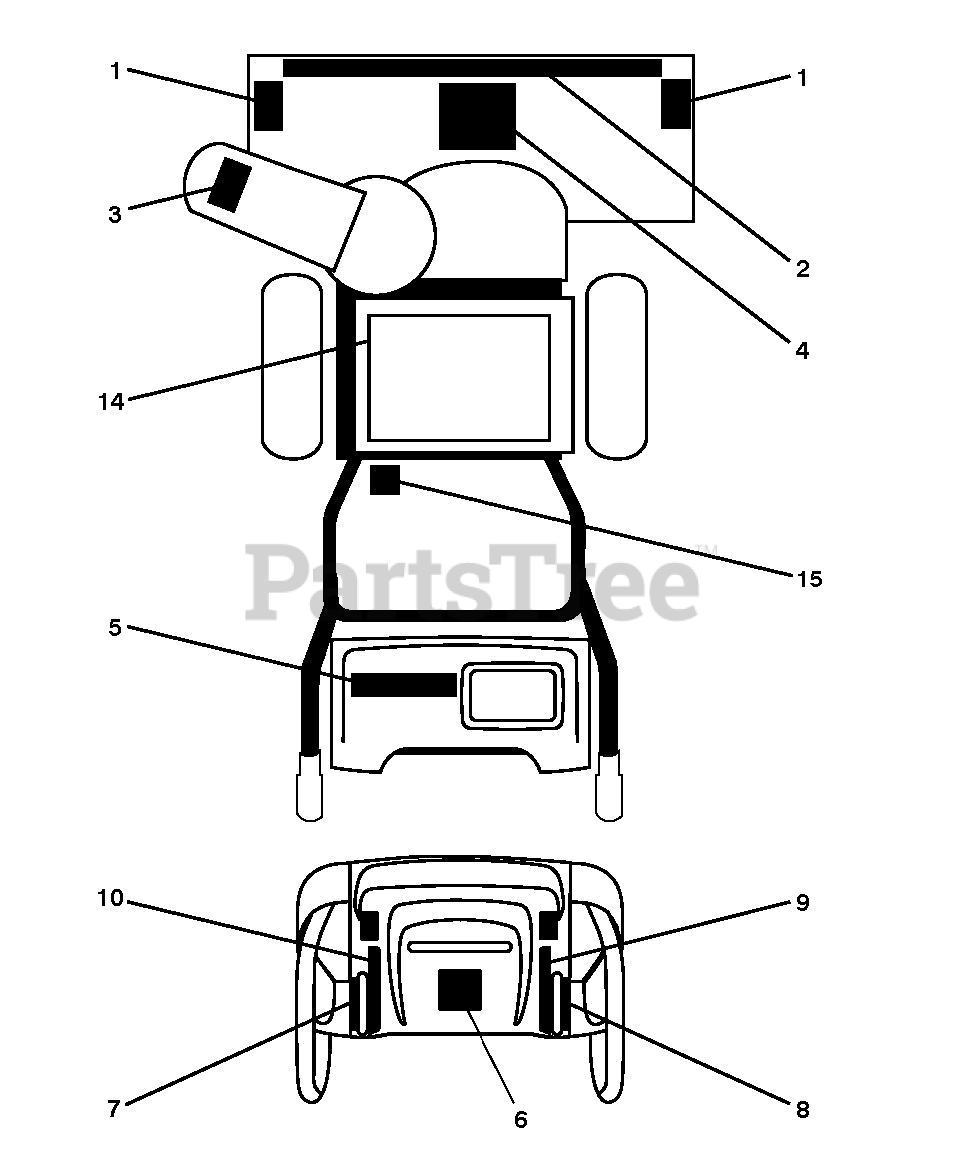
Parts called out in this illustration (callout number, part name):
1	DECAL.AUGER.SAFETY.
3	DECAL.CHUTE.SAFETY.
4	DECAL.AUGER."
6	DECAL.CONSOLE.INSTRUCTION
7	DECAL.POWER.STEER.LT.TRIG.INT
8	DECAL.POWER.STEER.RT.TRIG.INT
10	DECAL.REM.DEFLECTOR.LT
14	DECAL.BELT.GUARD.
15	DECAL.FENDER
